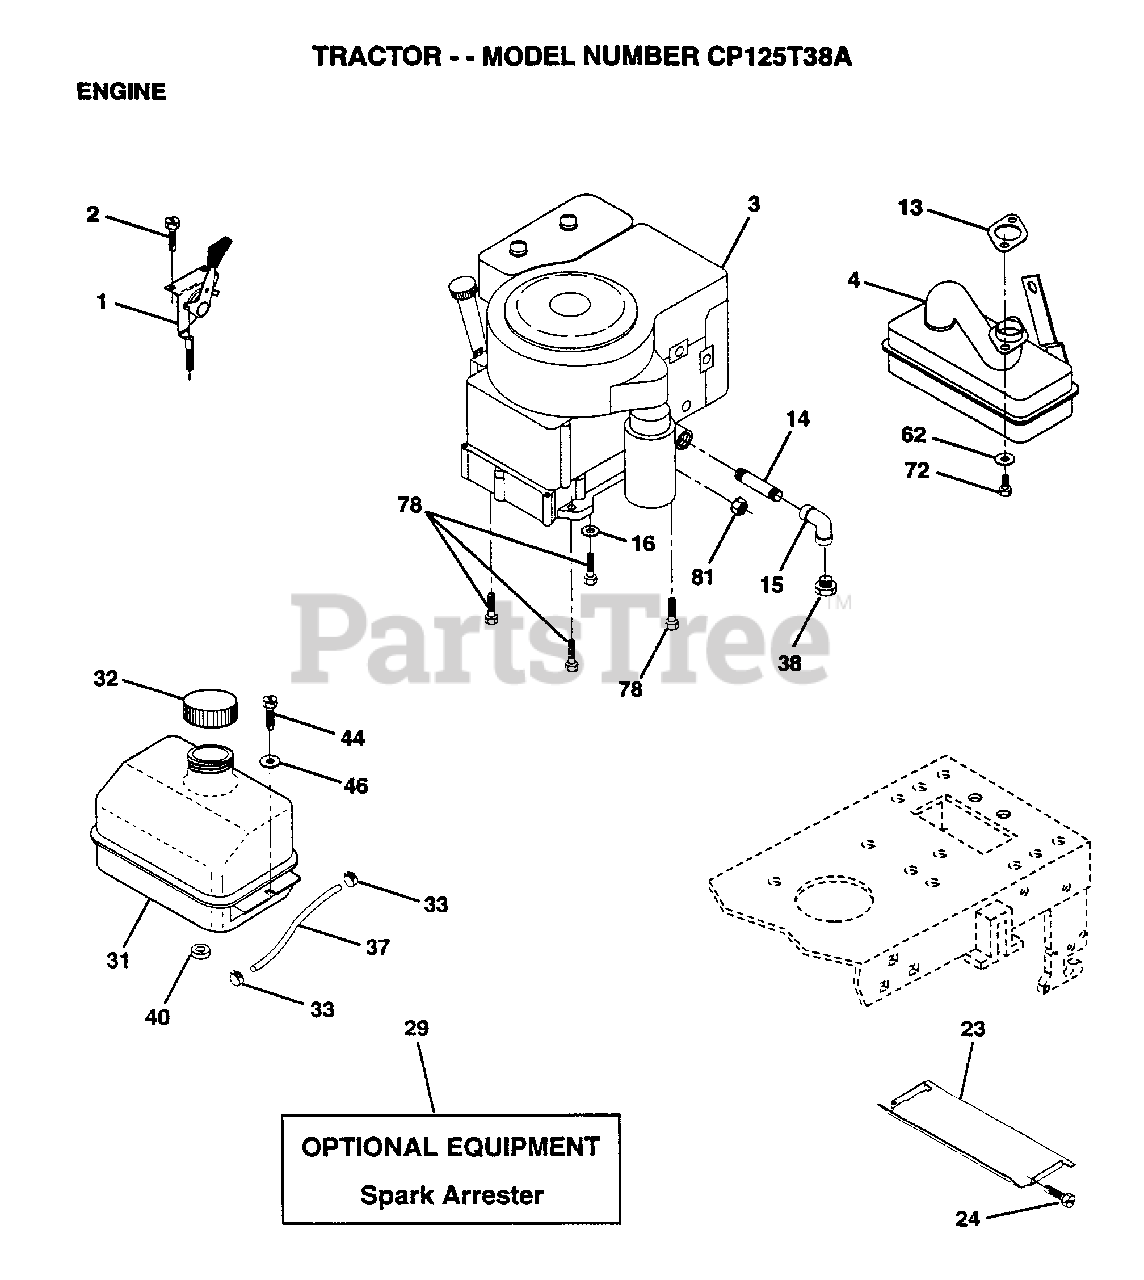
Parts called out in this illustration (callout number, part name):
2	AXLE ASM FRONT
3	SPINDLE LH
4	SPINDLE RH
5	WASHER .T
6	WASHER
7	WASHER
8	RING
9	COL. SRTG. BEAR.
11	LOCKWASHER
13	BEARING
14	BOLT HEX 5/8-11
15	"NUT-LOC,FLANGE LT"
16	AXLE PIN
17	SHAFT ASM STEERIN
18	THRUST WASHER
19	SUPPORT.SHAFT
21	LOCKWASHER
22	"SCREW,SPECIAL"
24	NYLINER T
25	"BRKT,STEERING"
26	BUSHING.DRAGLINK
27	GEAR SECTOR
28	WASHER
29	SCREW
30	COTTER PIN
32	TIE ROD
38	ST WHL INSERT CAP
39	WASHER T
40	GRIPCO NUT
41	ADAPTER-WHEEL LT
42	BOOT SHAFT STEER
43	WASHER
44	SHAFT EXT STEER
46	CAP
47	ZERK M
50	SCREW HEX CRT
51	NUT
54	BOLT
55	CLIP TINNERMAN
57	SUPPORT SHAFT STR
